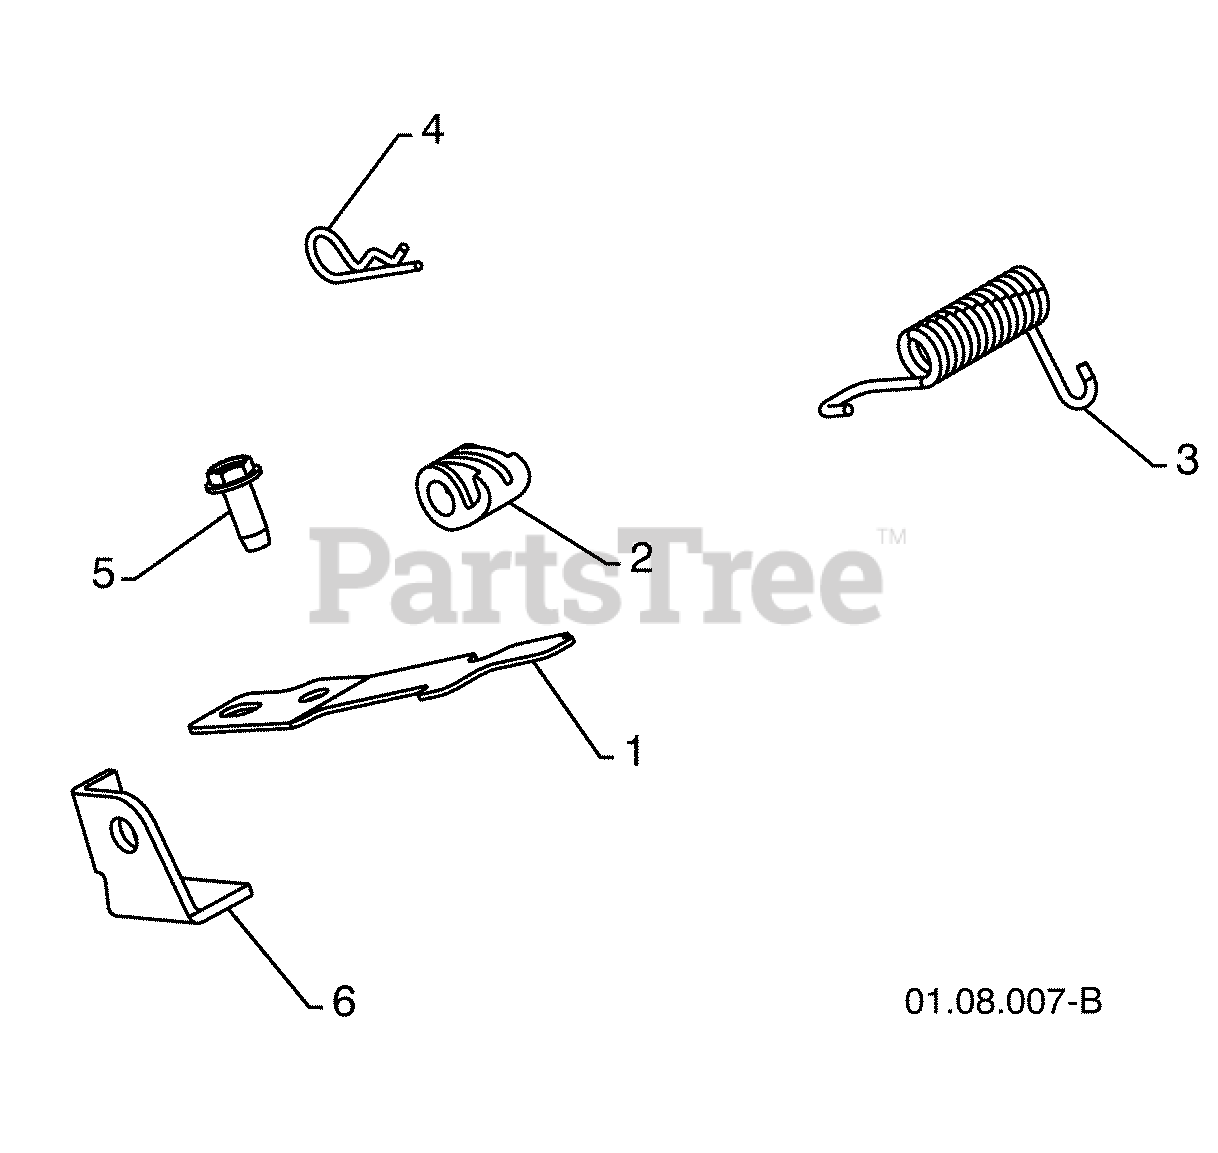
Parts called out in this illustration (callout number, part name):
1	INTERLOCK SPRING
2	INTERLOCK CAM
3	TORSION SPRING
5	SCREW 1/4-20 X .625
6	INTERLOCK STOP
